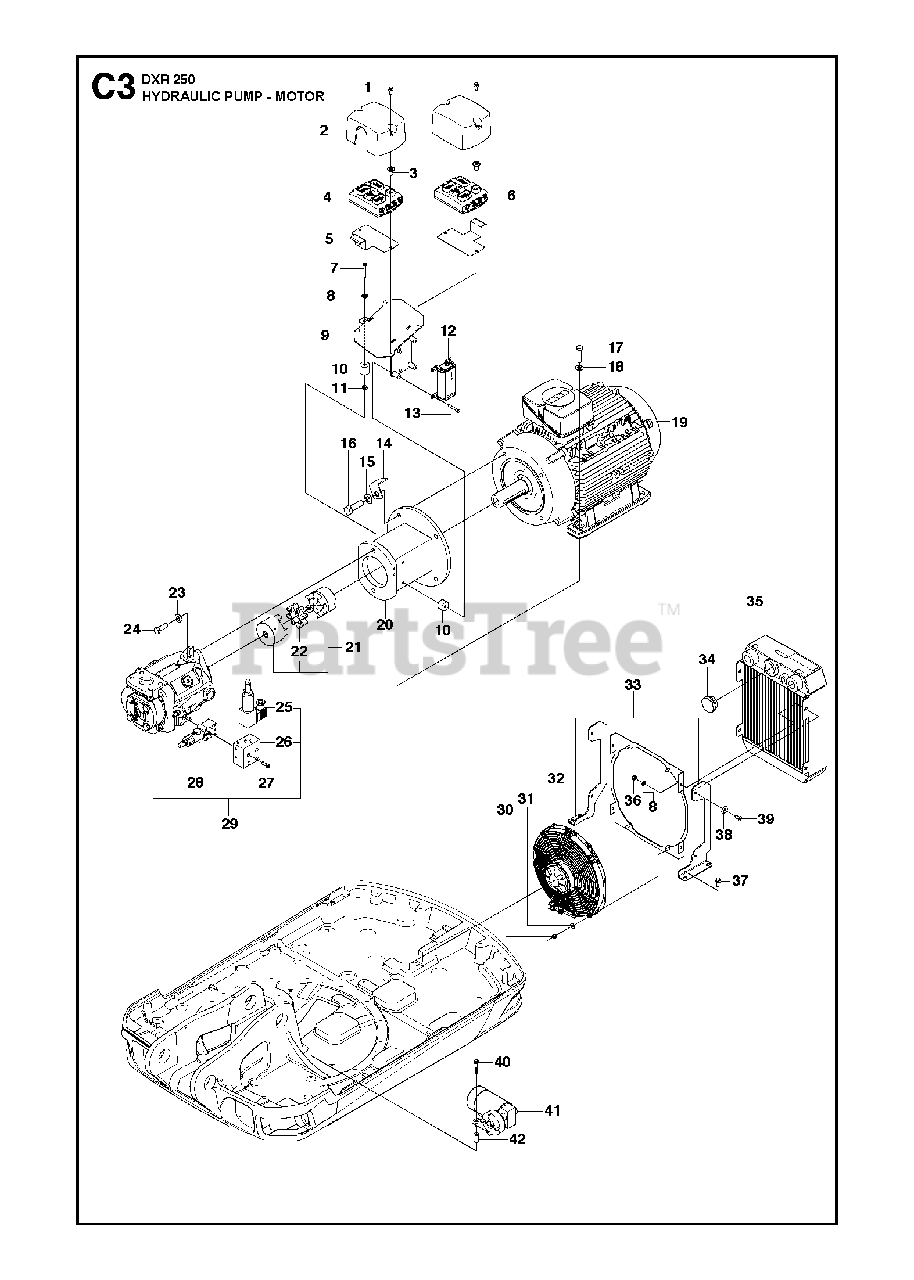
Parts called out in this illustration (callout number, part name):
11	HEXAGON NUT
34	VALVEBefore S/N 20151000046
34	VALVEFrom S/N 20151000046
39	SCREW IHCSFM
